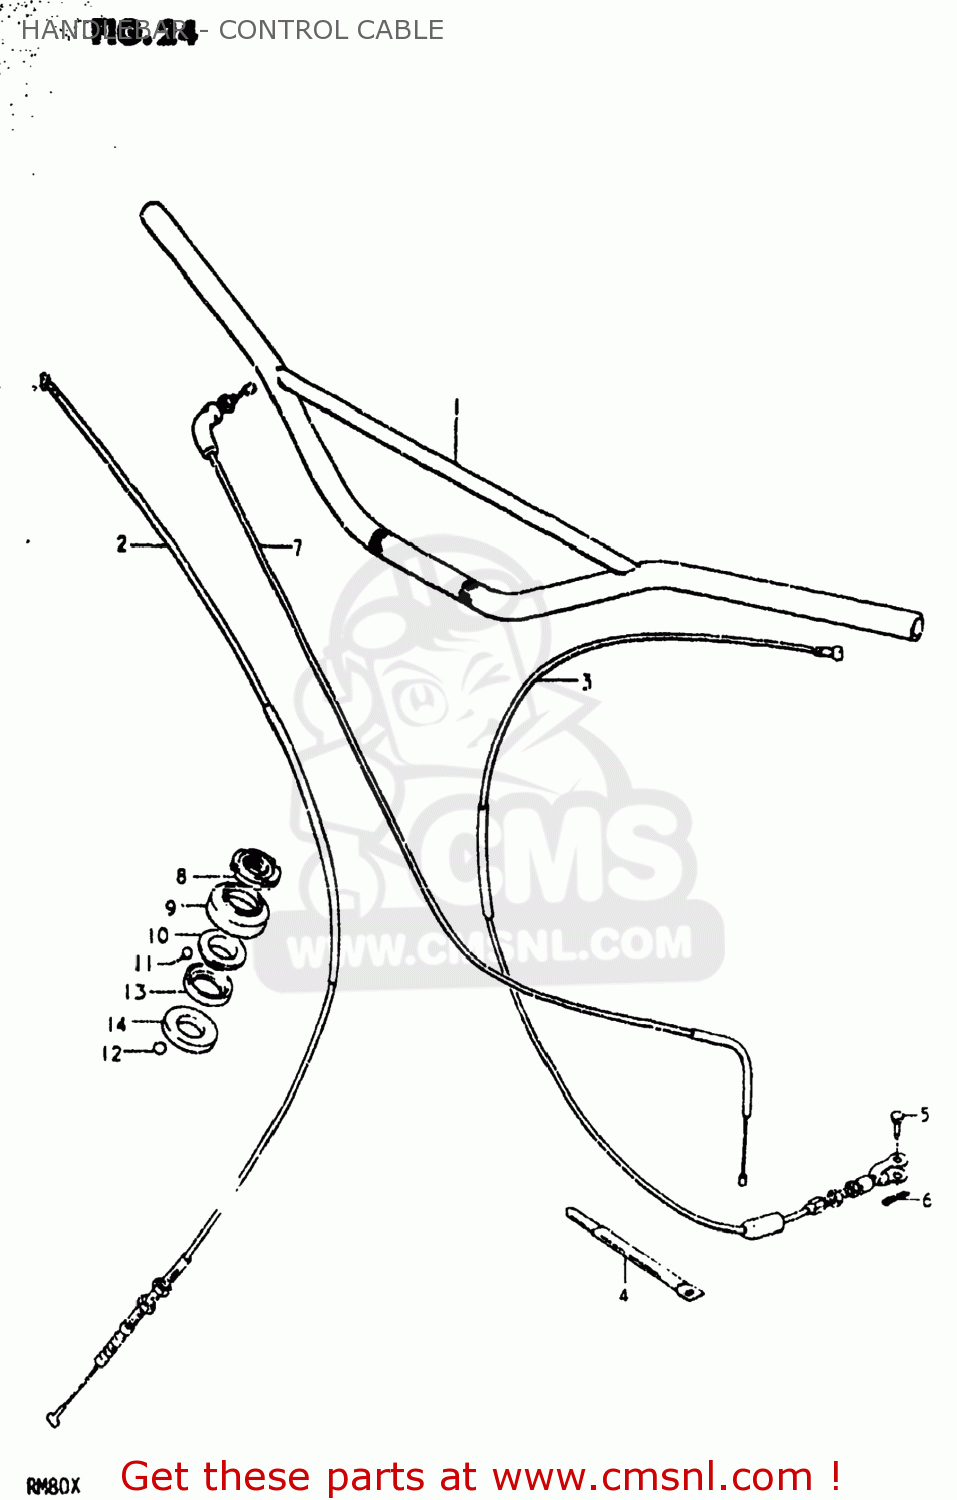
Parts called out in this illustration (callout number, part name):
1	HANDLEBAR
2	CABLE,FR BRAKE
3	CABLE ASSEMBLY,CLUTCH
4	CLAMP
5	PIN(L:13)
6	PIN
7	CABLE ASSEMBLY,THROTTLE
8	NUT,STEERING STEM(25X44X10)
9	DUST SEAL,STEERING UPR
10	RACE,STEERING OUTER UPR
11	BALL
12	BALL
13	RACE,STEERING INNER UPR
14	LACE,STEERING INNER LWR
